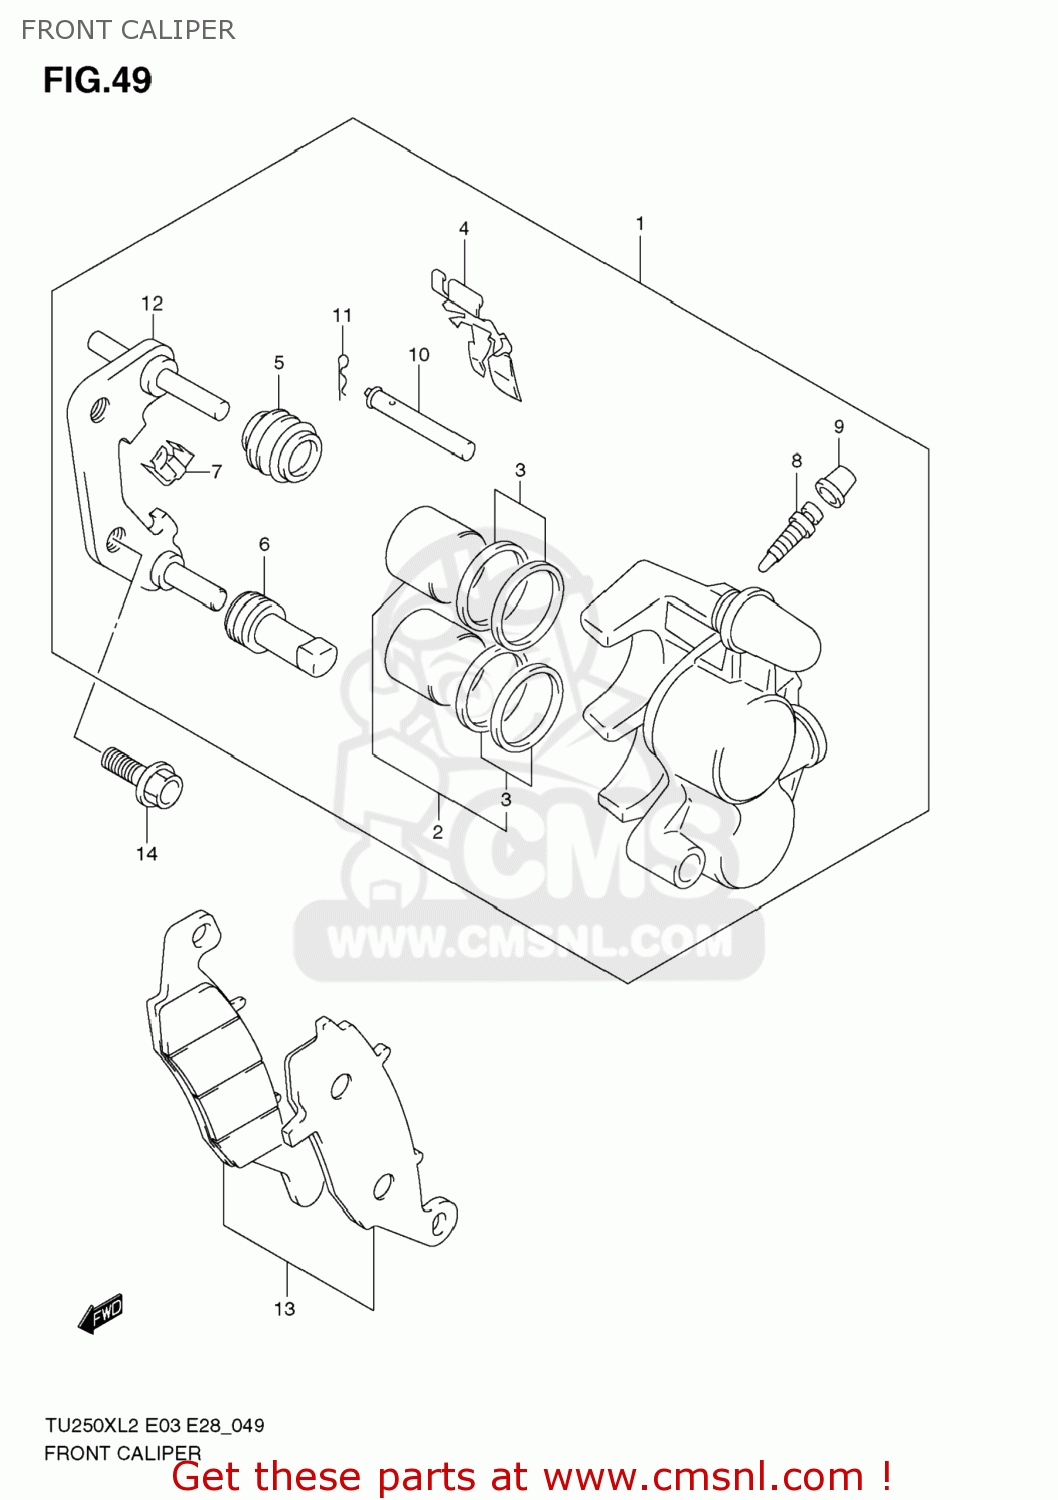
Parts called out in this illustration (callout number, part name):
1	CALIPER ASSY,FR,L
2	PISTON SET
3	SEAL SET,PISTON
4	SPRING,PAD,L
5	BOOT,AXLE
6	INSULATOR,AXLE
7	GUIDE,PAD
8	BLEEDER
9	CAP,BLEEDER PLUG
10	PIN,PAD
11	CLIP,PAD PIN
12	CARRIER,CALIPER,L
13	PAD SET (NAS)
14	BOLT
